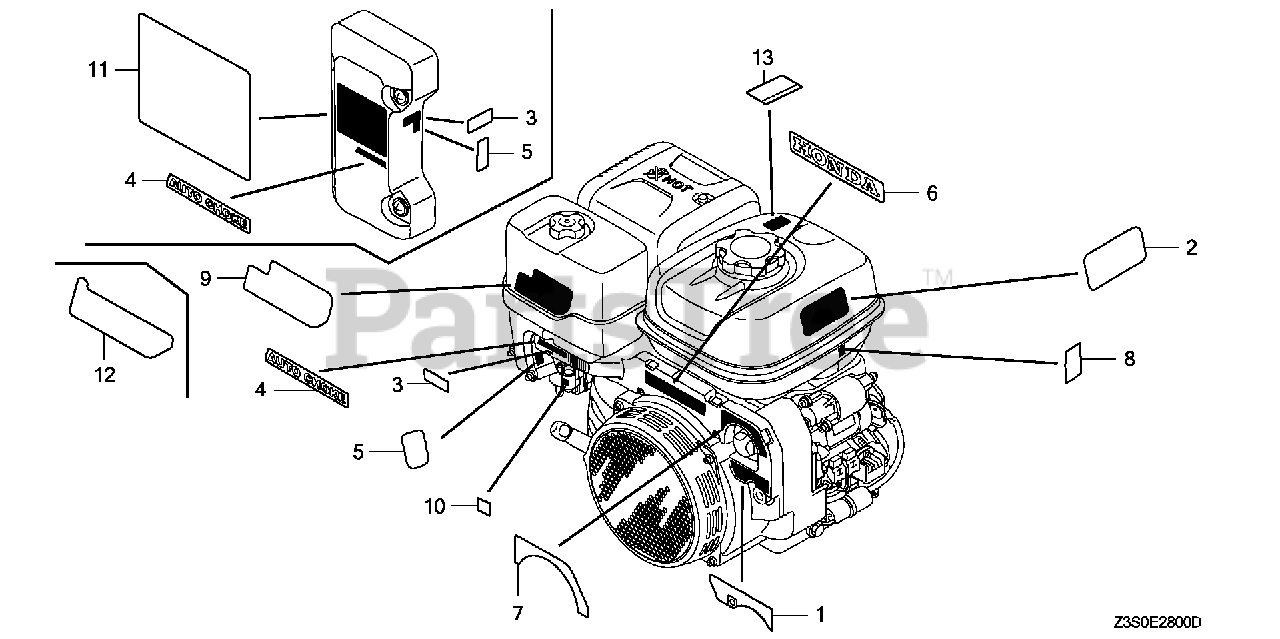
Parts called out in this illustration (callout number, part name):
4	MARK, CHOKE
5	MARK, CHOKE (CAUTION)
11	MARK, SALES POINT
